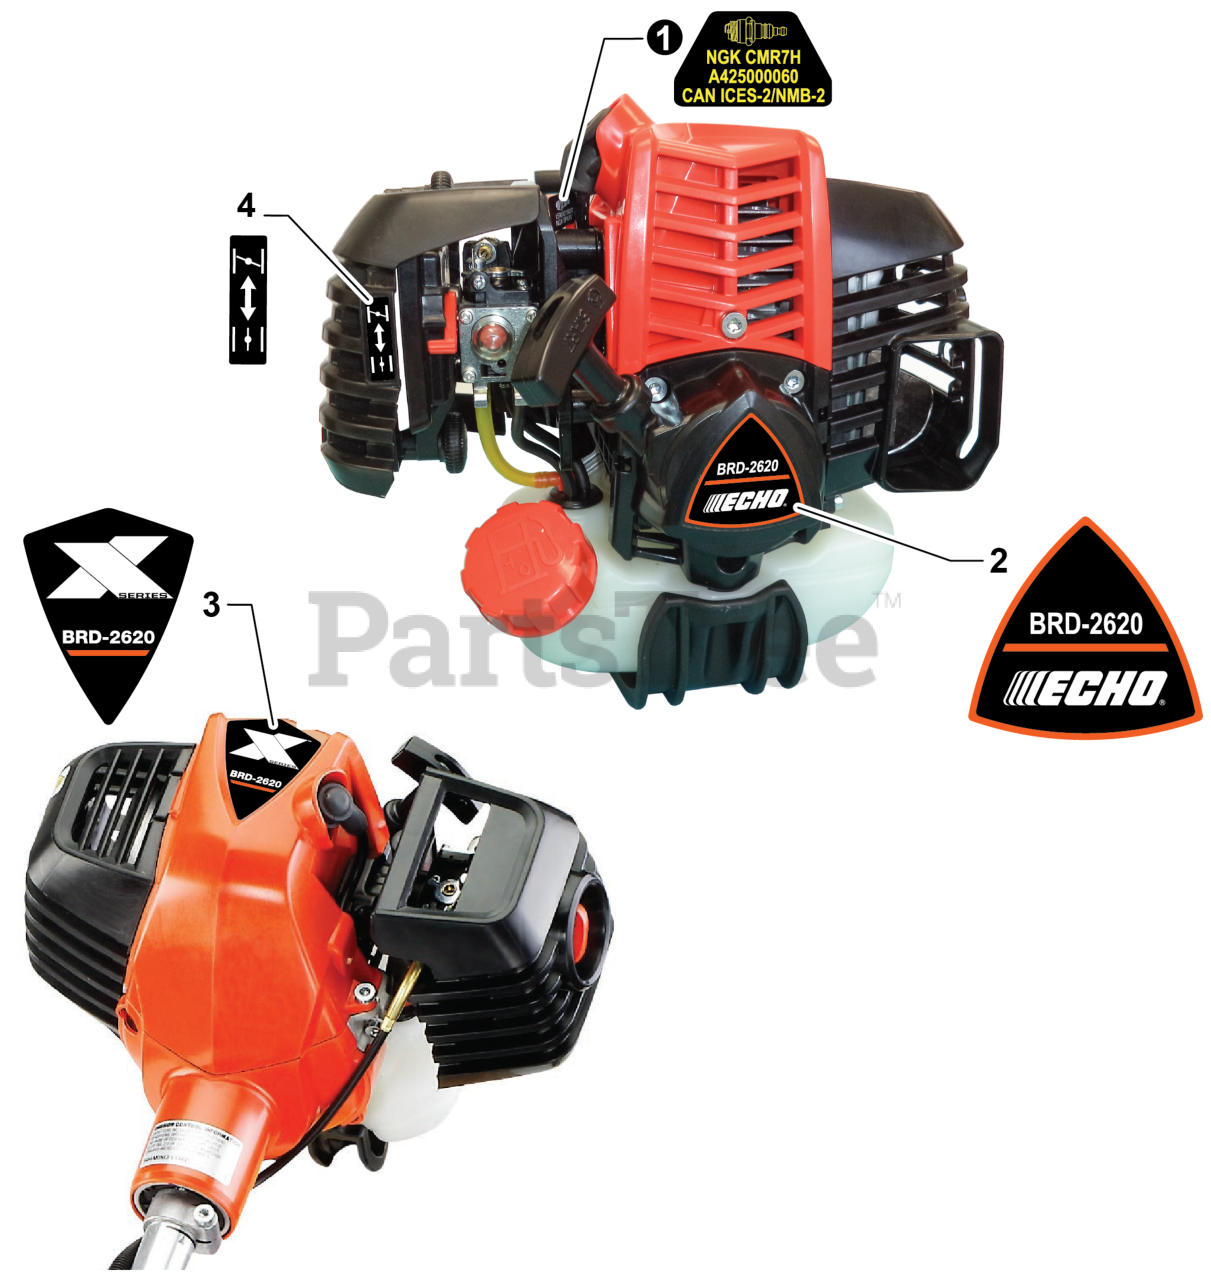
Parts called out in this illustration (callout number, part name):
1	LABEL - SPARK PLUG - CMR7H
2	LABEL - RECOIL STARTER - BRD-2620
3	LABEL - MODEL BRD-2620
4	LABEL - CHOKE
